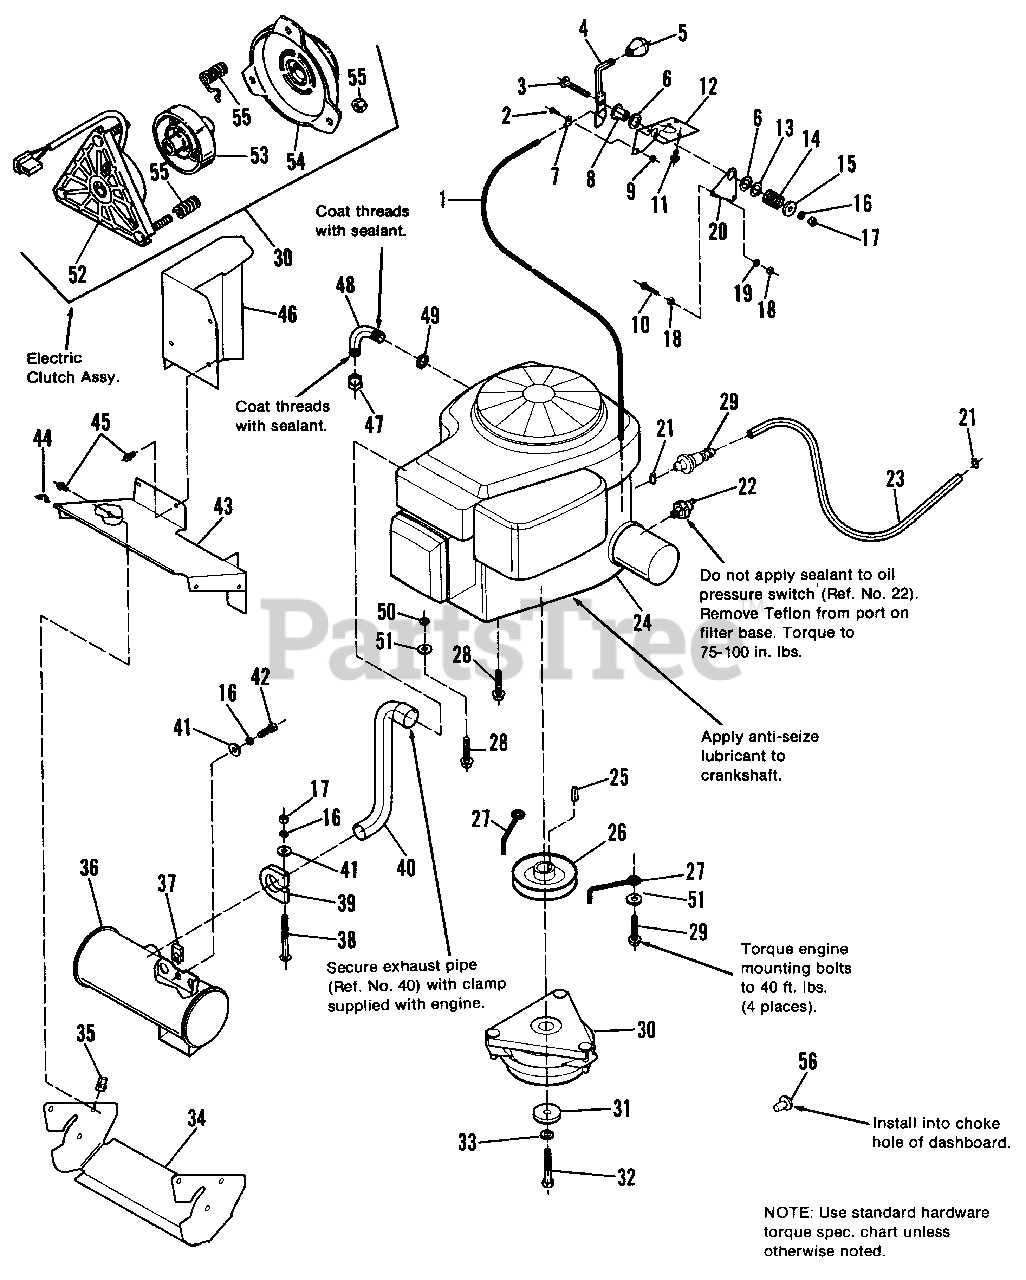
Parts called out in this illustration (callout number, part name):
1	CABLE, Throttle
2	SCREW, Trusshead, 10-32 x 1/2
3	BOLT, Carriage, 5/16-18 x 1-3/4
4	HANDLE, Throttle
5	KNOB, Throttle
6	WASHER, Nylon
7	CLIP, Bowden Wire
9	NUT ASSY., 10-32
10	CAPSCREW, Hex, 1/4-20 x 1-1/4
11	SCREW, Plastite, 1/4-20 x 5/8
12	BRACKET, Throttle Mounting
15	WASHER, Plain, 5/16
16	LOCKWASHER, 5/16
17	NUT, Full, Hex, 5/16-18
18	NUT, Full, Hex, 1/4-20
19	LOCKWASHER, 1/4
20	PLATE, Spring
21	CLAMP, Hose
22	SWITCH, Oil Pressure
23	HOSE, Fuel, 38" Long (Cut to length)
24	ENGINE, Single Cylinder (Briggs & Stratton)
25	KEY, Hi-Pro
26	PULLEY ASSY.
28	SCREW, Taptite, 3/8-16 x 1-1/4
29	FUEL FILTER
30	ELECTRIC CLUTCH (Inc. Ref. Nos. 52-55)
32	CAPSCREW, 7/16-20 x 2-1/2
33	LOCKWASHER, 7/16
34	DUCT, Lower Muffler
35	NUT, Pal, 1/4-20
36	MUFFLER ASSY.
37	NUT, Pal, 5/16-18
38	CARRIAGE BOLT, 5/16-18 x 2-3/4
39	CLAMP, Muffler
40	PIPE, Exhaust
41	WASHER, Plain, 5/16
42	CAPSCREW, Hex, 5/16-18 x 1
43	DUCT, Top, Muffler
44	CLIP
45	SCREW, Flange Whiz, 1/4-20 x 5/8
46	SHROUD ASSY.
50	LOCKWASHER, External Tooth
51	WASHER, Plain, 13/32
52	FIELD ASSY., Clutch
53	ROTOR ASSY.
54	ARMATURE ASSY., Clutch
55	ACCESSORY KIT
56	FASTENER, Panel
